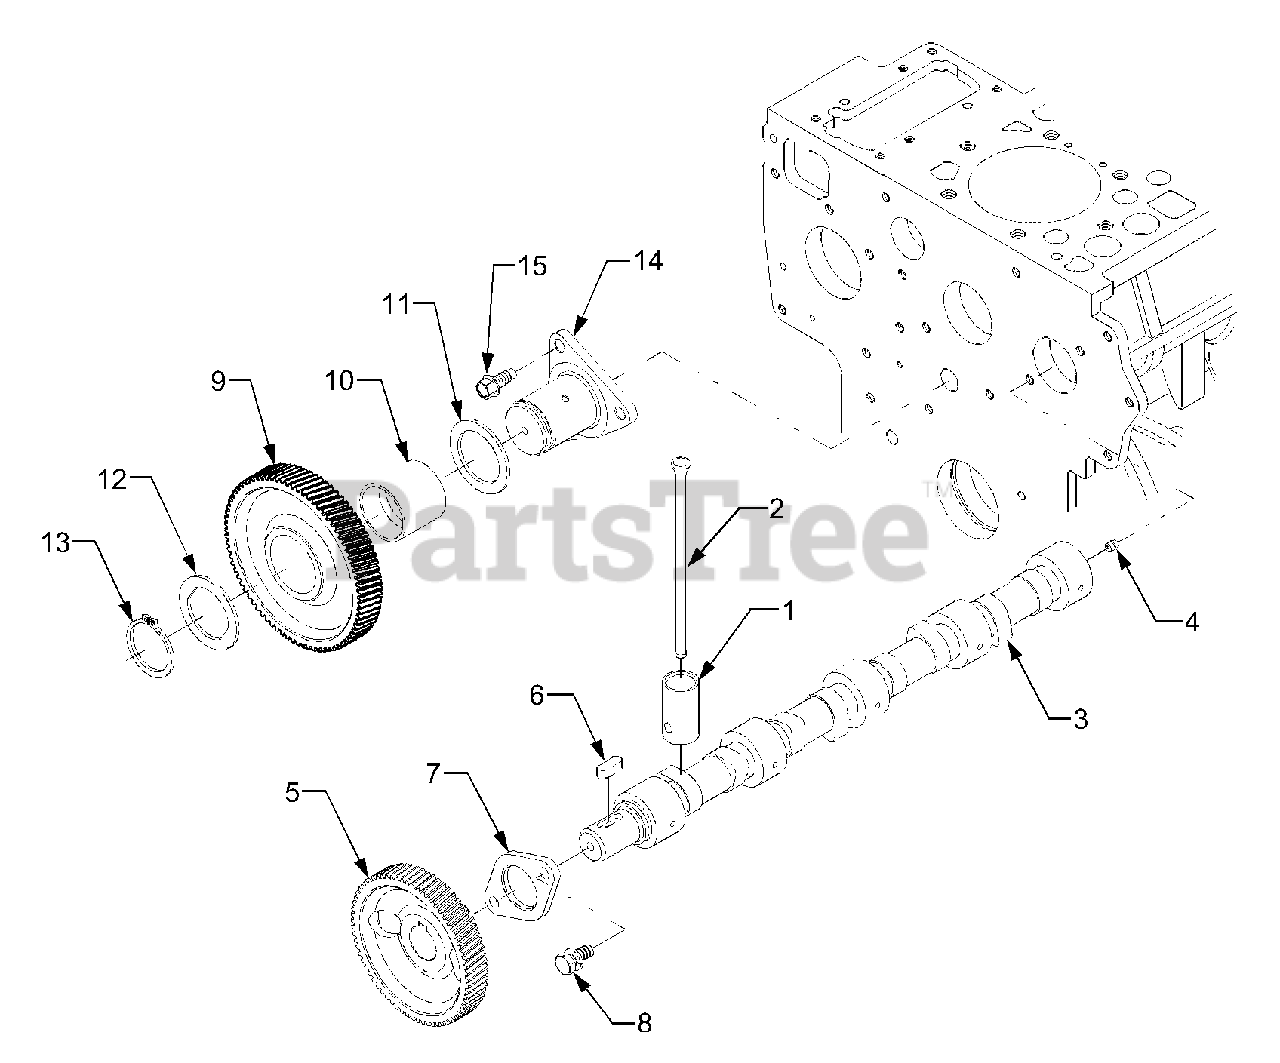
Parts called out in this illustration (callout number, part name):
2	Rod, Push
3	Camshaft Ass'y
5	Gear, Camshaft
7	Stopper, Camshaft
9	Idle Gear Ass'y
10	Bush, Idle Gear
14	Shaft, Idle Gear
